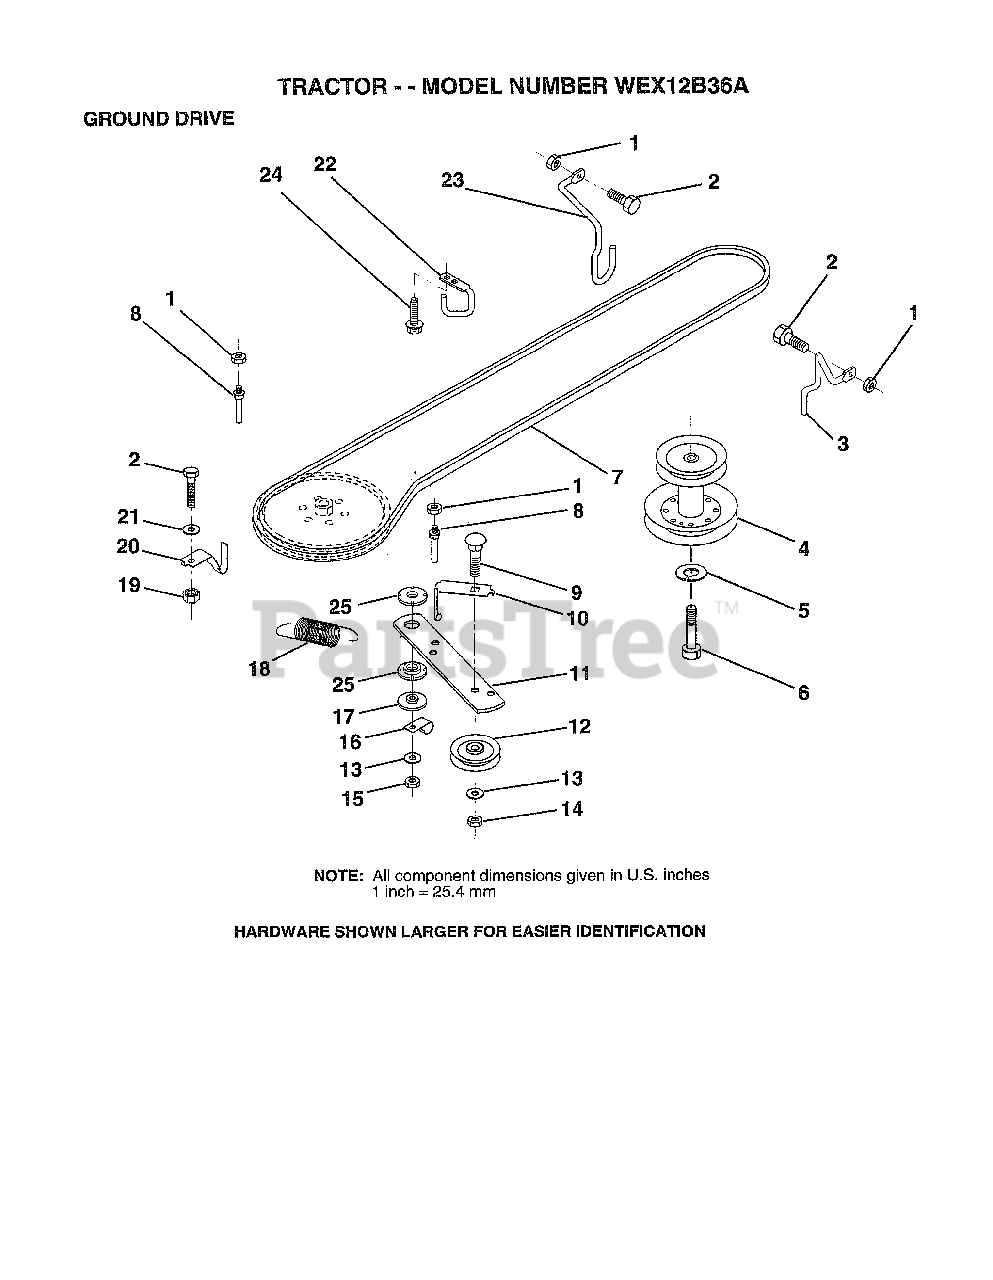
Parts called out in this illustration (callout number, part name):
2	BOLT
3	KEEPER RH
4	PULLEY.ENGINE.LR
5	LOCKWASHER
6	HEX BOLT
7	V BELT
8	"KEEPER,DRIVE BELT"
9	BOLT
10	"KEEP,IDLER DR BEL"
11	ARM-IDLER.DR.GRND
12	PULLEY.IDLER.FLAT
13	WASHER
14	LOCKNUT
16	"CLIP,INSULATOR"
17	SPACER
20	KEEPER.BELT.T/A
21	WASHER
22	"KEEPER,FRA DR BEL"
23	KEEPER MOWER LH
24	SCREW
25	BUSHING.NYLON
